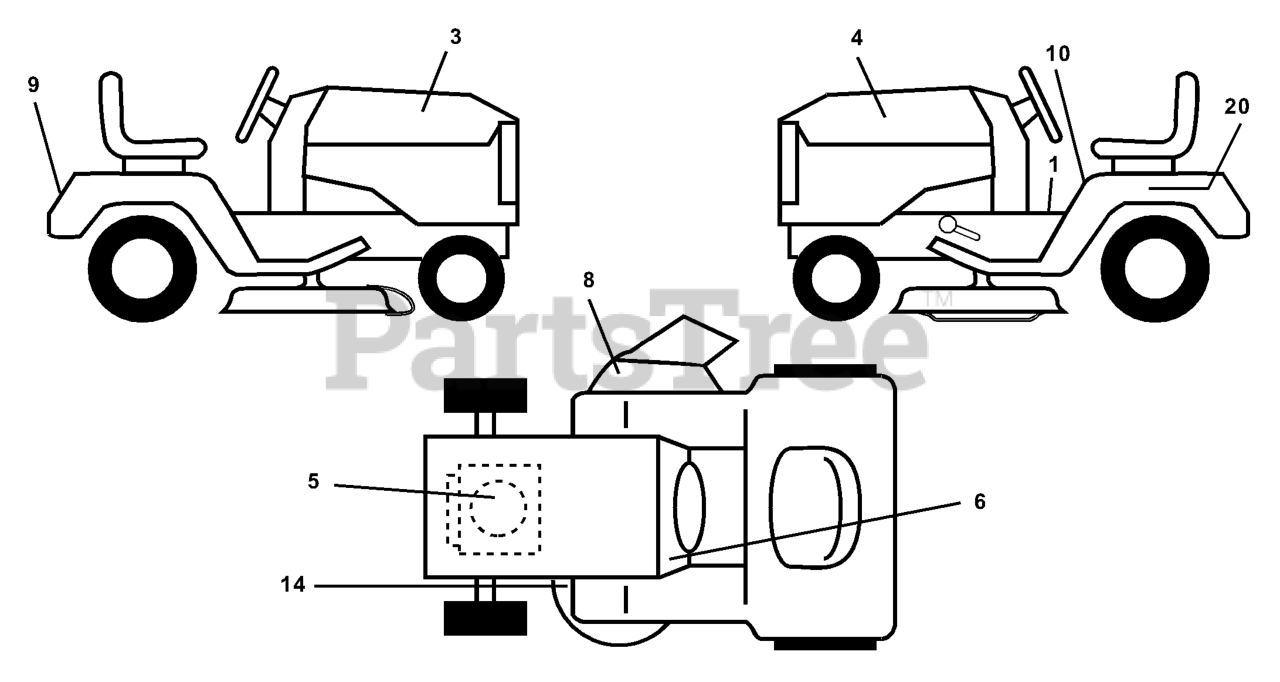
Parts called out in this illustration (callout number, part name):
3	DECAL, HOOD RH LTH120
4	DECAL, HOOD LH LTH120
5	DECAL-ENGINE HP
8	DECAL WARNING (ENGLISH/FRENCH)
9	DECAL FENDER HUSQ
10	DECAL FENDER DANGER
14	DECAL V-BELT SCHEMATIC
20	DECAL BTRY SYMBOLS
